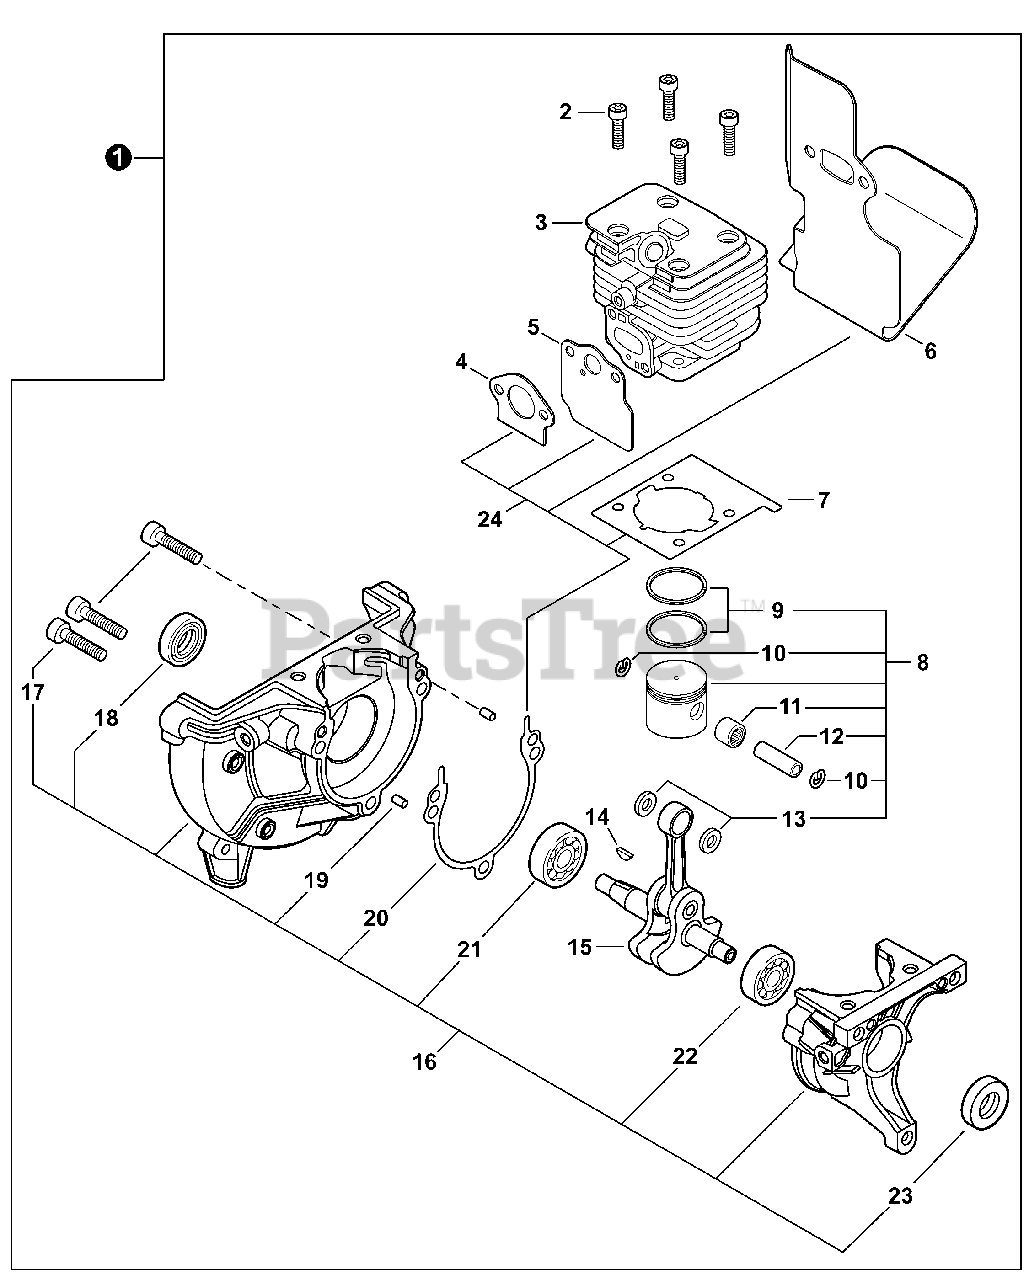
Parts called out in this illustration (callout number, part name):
1	SHORT BLOCK
2	BOLT, TORX 5×20
3	CYLINDER
4	GASKET, INTAKE
5	HEAT SHIELD, INTAKE
6	HEAT SHIELD, EXHAUST
7	GASKET, CYLINDER
8	PISTON KIT
9	RING, PISTON
10	RING, SNAP
11	BEARING, NEEDLE 9
12	PIN, PISTON
13	WASHER, THRUST 9×12×15×3
14	KEY, WOODRUFF
15	CRANKSHAFT ASSY
16	CRANKCASE KIT
17	BOLT, TORX 5×25
18	SEAL, OIL 10
19	PIN, LOCATING 4×8
20	GASKET, CRANKCASE
21	BEARING, BALL
22	BEARING, BALL 6001
23	SEAL, OIL 12
24	GASKET KIT
